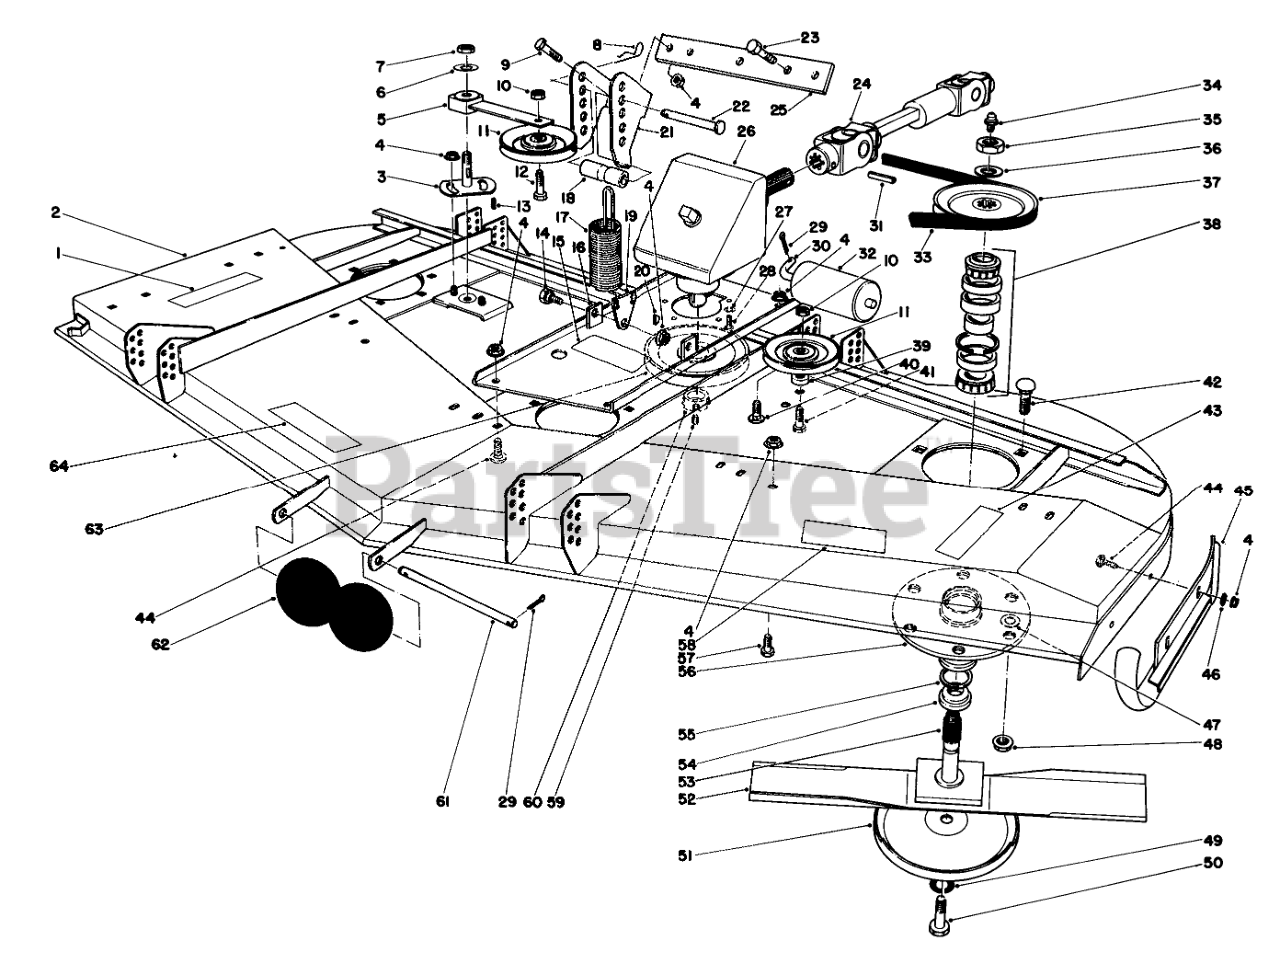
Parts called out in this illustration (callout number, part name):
1	DECAL-CAUTION, DEFLECTOR
2	62 DECK WA R
3	Plate-Idler
4	216 Washer
5	IDLER ARM ASM
6	WASHER-FLAT
7	NUT-LOCK, NI
8	PIN-HAIR
9	SCREW-HH
10	NUT-HEX
11	Pulley
12	SCREW-HH
13	KEY-SQUARE
14	BOLT-SHOULDER
15	Decal-Caution
16	GEARBOX BASE WA R
17	Spring-Extension
18	SPACER
19	SPRING END R
20	KEY-WOODRUFF
21	SPRING BRACKET R
22	PIN-CLEVIS
23	SCREW-HH
24	Pivot Nut
25	BRKT MOUNT R
26	GEAR BOX ASM
27	WASHER-LOCK
28	SCREW-HSH
29	PIN-COTTER
30	SHAFT-ROLLER, REAR
31	PIN-ROLL
32	ROLLER-DECK
33	V-BELT
34	FITTING-GREASE
35	NUT-HEX
36	Washer
37	PULLEY AND HUB ASM
38	BEARING ASM
39	SPACER
40	SCREW-CARR
41	SCREW-HH
42	SCREW-CARR
43	DECAL-CAUTION, BLADE
44	SCREW-CARR
45	L.H. Skid
46	LOCKWASHER-PYRAMID
47	WASHER-FLAT
48	NUT-HF
49	WASHER-LOCK
50	SCREW-BLADE
51	Cup-Scalp
52	Blade
53	SHAFT
54	SPACER
55	SEAL-OIL
56	Housing-Spindle
57	SCREW-HH
58	Decal-Rear Weight
59	SCREW-SET, HSH
60	BUSHING-LOCK, TAPER
61	SHAFT-ROLLER
62	ROLLER
63	PULLEY WA BO
64	Decal-Caution
